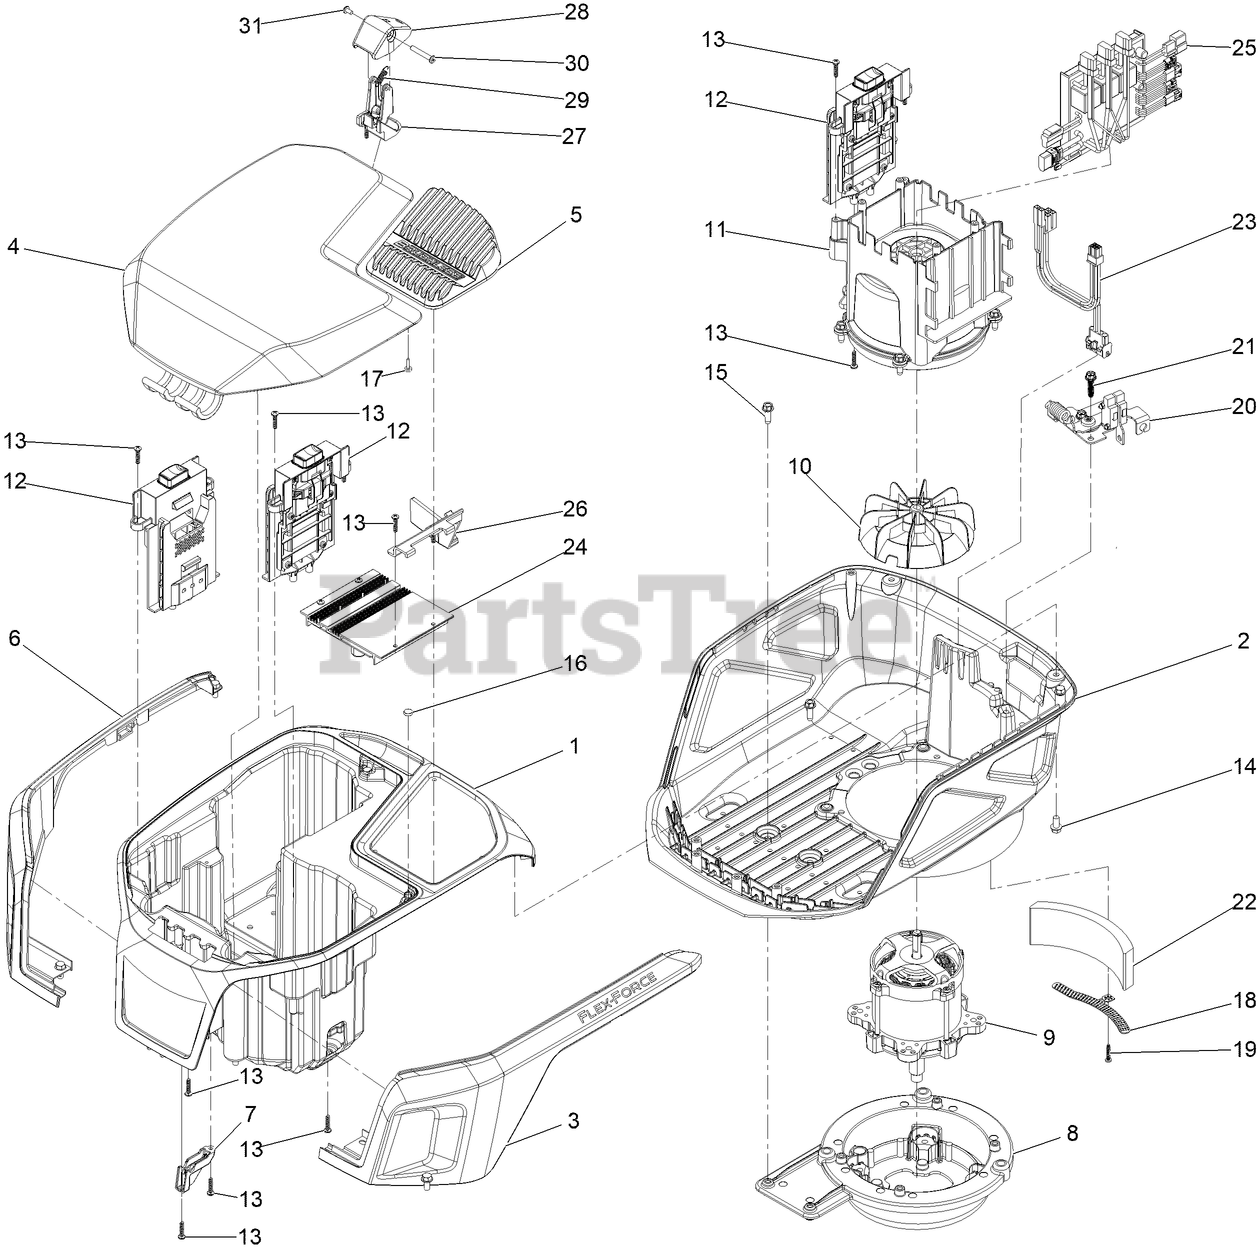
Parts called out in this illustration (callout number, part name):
1	BUCKET-BATTERY
2	SHROUD-LOWER
3	TRIM-SHROUD, LH
4	LID-MOTOR
5	HEATSINK-CONTROLLER
6	TRIM-SHROUD, RH
7	BRACKET-SUPPORT, LID
8	MOUNT-BASE, MOTOR
9	MOTOR-60V
10	FAN-MOTOR
11	SHROUD-MOTOR
12	RECEIVER-BATTERY
13	SCREW-PPH
14	SCREW-PLASTITE
15	SCREW-HWHTF
16	MAGNET
17	SCREW-PPH
18	BRACKET-FOAM
19	SCREW-PLASTIC, PPH
20	BAIL SWITCH ASM
21	SCREW-FLANGE, PLASTIC
23	HARNESS-WIRE
24	CONTROLLER-PMU
25	CONTROLLER-MOTOR
26	BRACKET-PMU
27	LIDLOCK-BASE
28	LIDLOCK-LEVER
29	SPRING
30	SCREW-PIN, HINGE
31	SCREW-PIN
